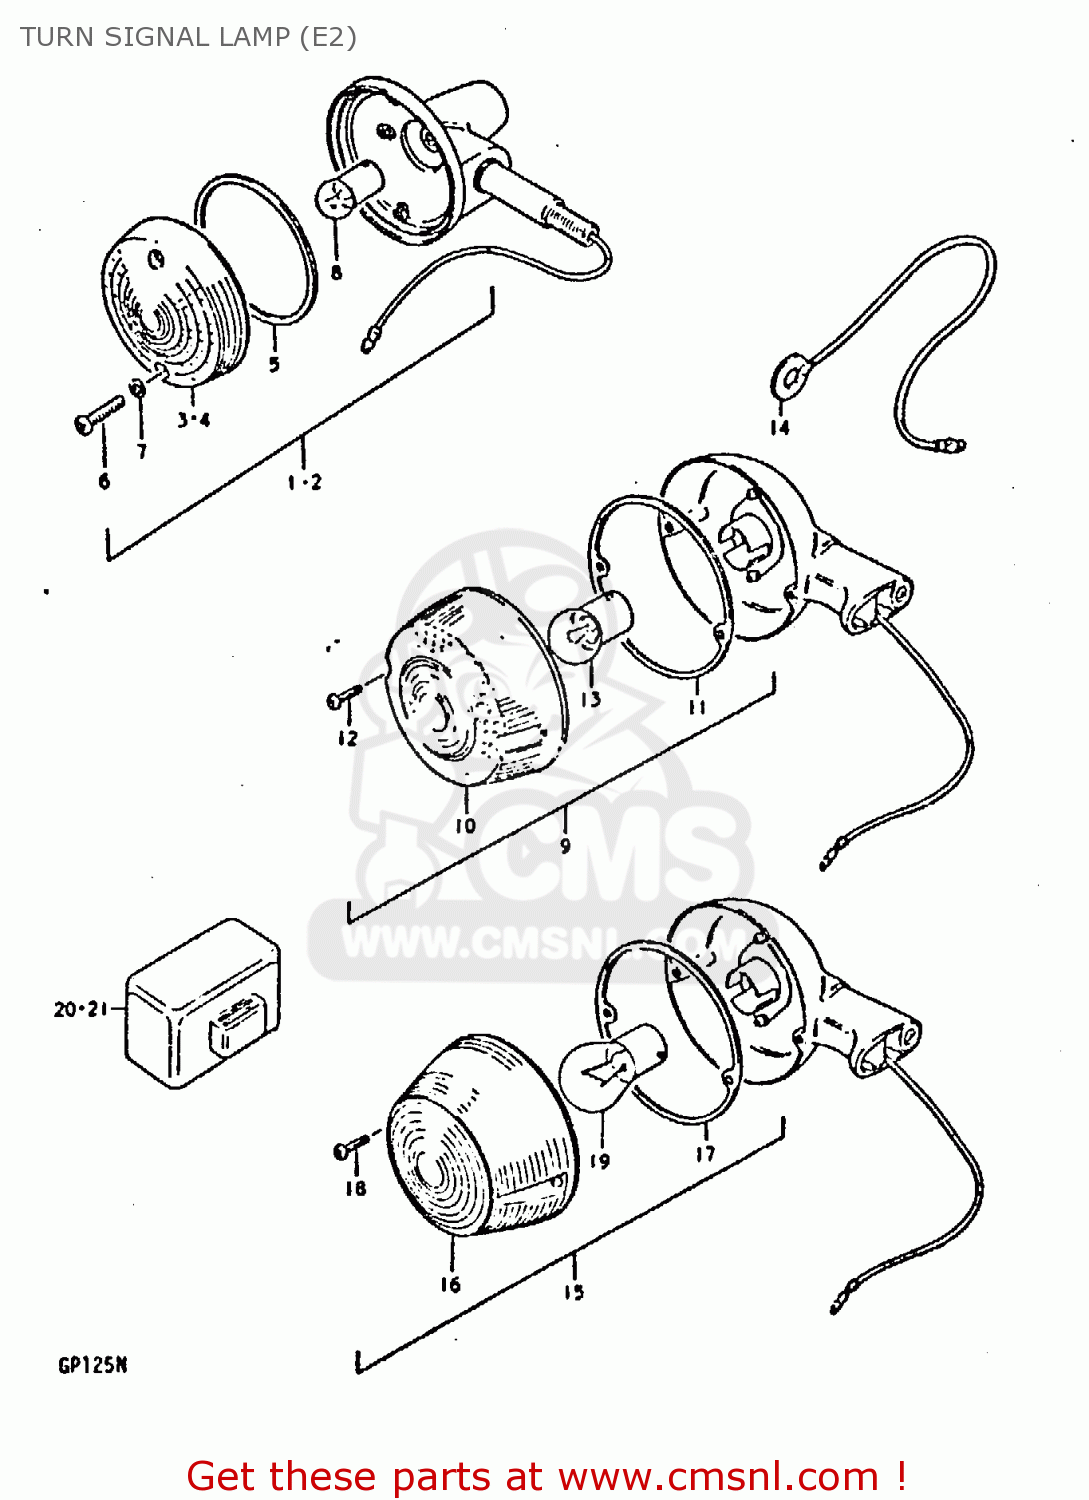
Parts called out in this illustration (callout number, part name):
14	LEAD WIRE,EARTH
15	LAMP ASSY, REAR TURN SIGNAL
16	LENS,TURNSIGNAL
17	GASKET (NAS)
18	SCREW
19	BULB (6V,18W)
21	RELAY,TURN SIGNAL
